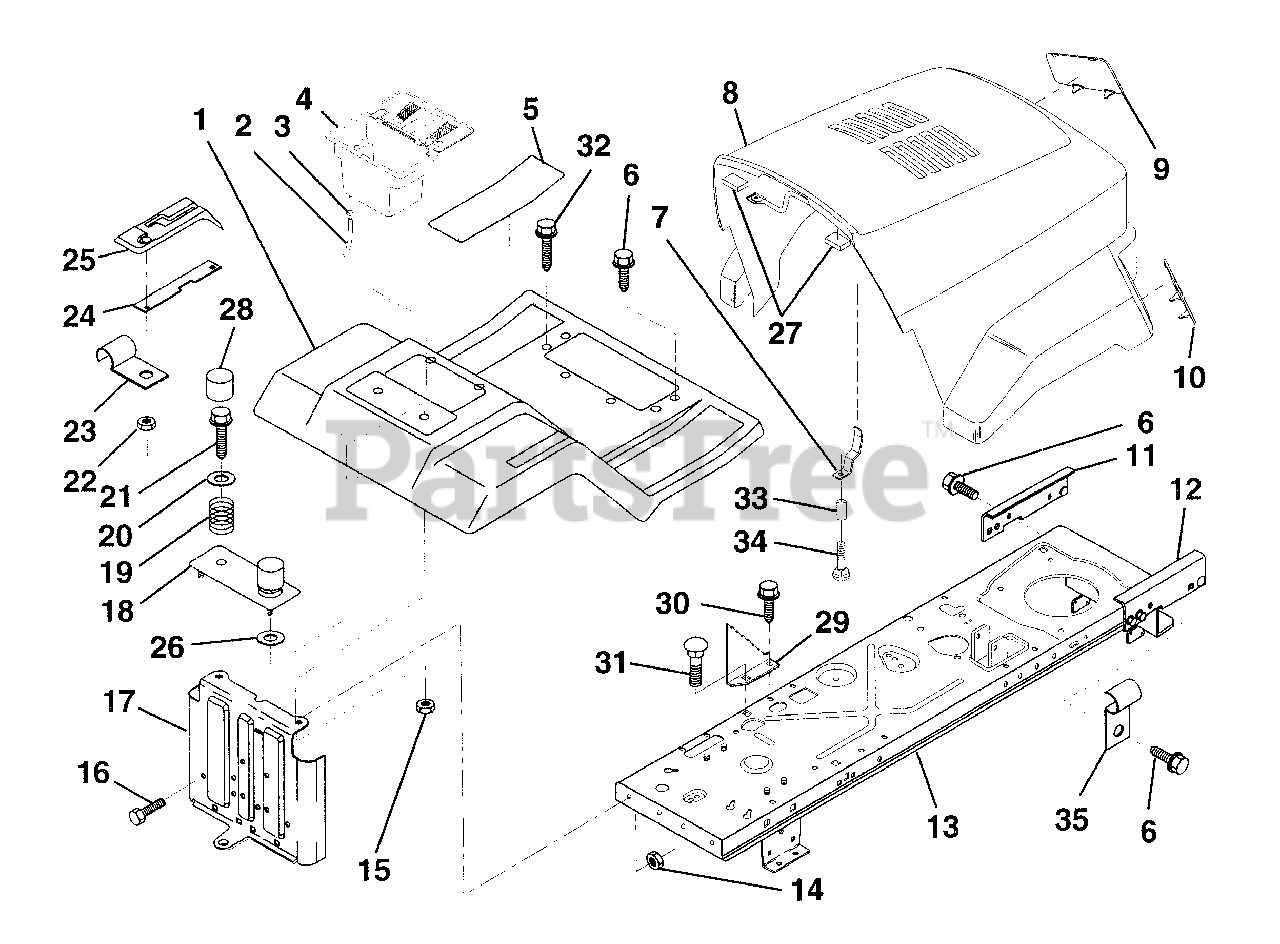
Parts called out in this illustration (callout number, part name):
1	Fender/Footrest
2	Tube, Battery Drain
3	Clamp, Hose
4	Case, Battery
5	Pad, Footrest
6	Screw, Hex Washer Head, Thd., Roll. 5/16-18 x 3/4
7	Latch, Hood
8	Hood and Grill Assembly
9	Lens, L.H.
10	Lens, R.H.
11	Pivot Bracket Assy., Chassis, L.H.
12	Pivot Bracket Assy., Chassis, R.H.
13	Assembly, Frame
14	Nut, Hex, Crownlock 5/16-18
15	Nut, Hex, Keps 1/4-20 UNC
16	Bolt, Hex Head 5/16-18 UNC x 3/4
18	Plate Assembly, Battery
19	Spring, Compression, Seat
20	Washer 13/32 x 1-1/4 x 12 Gauge
21	Screw, Hex Washer Head, Thd., Roll. 3/8-16 x 3/4
22	Nut, Self-Threading, Washer Head 3/16
23	Clip, Insulated
24	Bar, Shift Lock
25	Console, Shift Control
26	Washer 9/32 x 7/8 x 13 Gauge
27	Bumper, Hood
28	Cap, Seat Spring
29	Plate, Depth Stop
30	Screw, Thd., Roll. 5/16-18 x 1/2
31	Bolt, Carriage 5/16-18 x 3/4
32	Screw, Thd., Roll. 5/16-18 x 1
33	Spacer
34	Bolt, Carriage 1/4-20 x 1-1/2
35	Clip, Fuel Line
